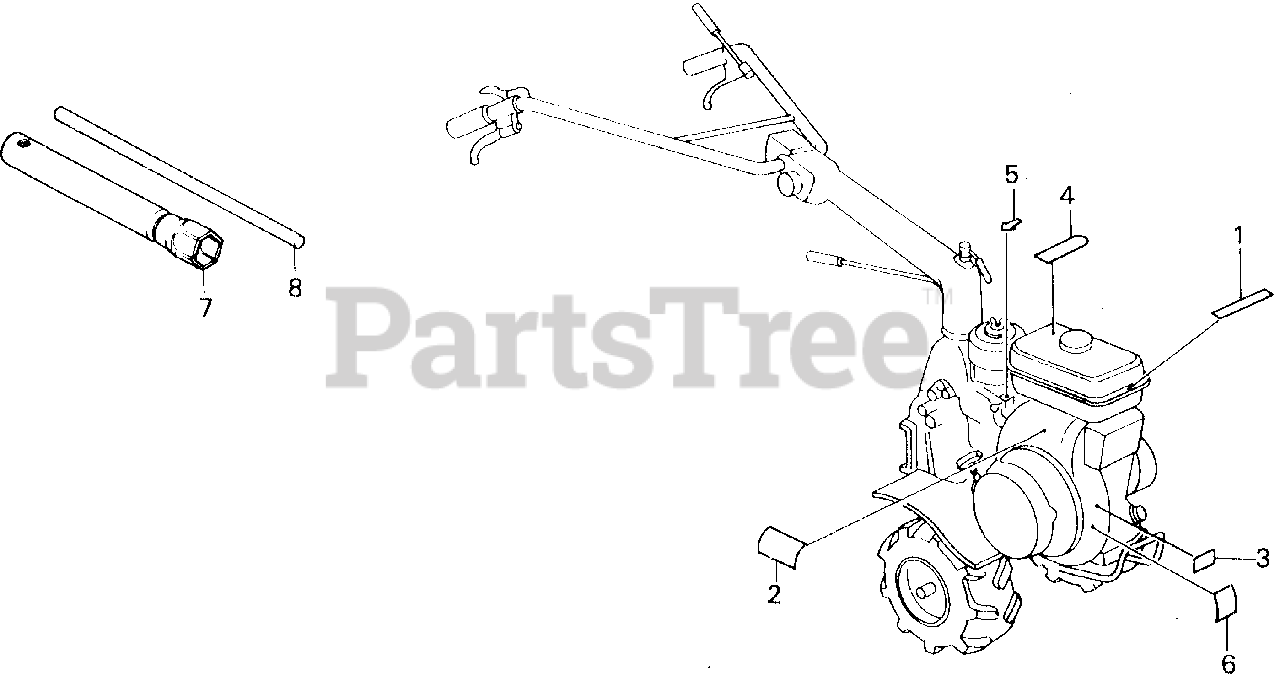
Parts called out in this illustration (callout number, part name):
1	MARK, TOP COVER
2	MARK, FAN COVER
4	MARK A, CAUTION (ENGLISH/FRENCH)
5	MARK, CHOKE
6	MARK, OIL CAUTION
7	WRENCH, SPARK PLUG (NOT AVAILABLE)
8	HANDLE, BOX WRENCH
